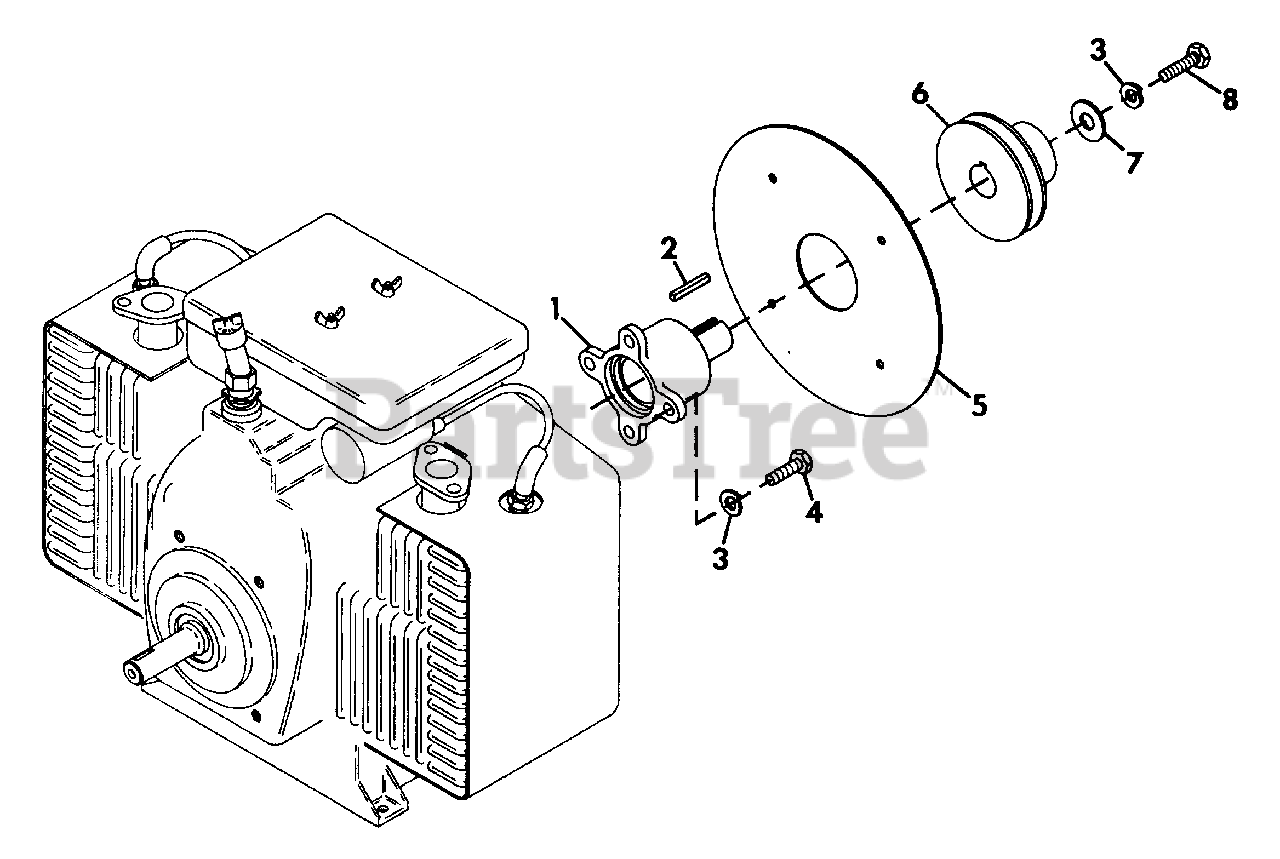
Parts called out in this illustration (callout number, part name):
1	ADAPTOR, DRIVE KOHLER
2	KEY, SQUARE .250X1.250
3	WASHER, LOCK 3/8
4	BOLT, HEX 3/8-16X1.00
5	SCREEN, GRASS KOHLER
6	SHEAVE, ENGINE
7	WASHER, FLAT 1.25X.50 HARD
8	BOLT, HEX 3/8-16X1.25
